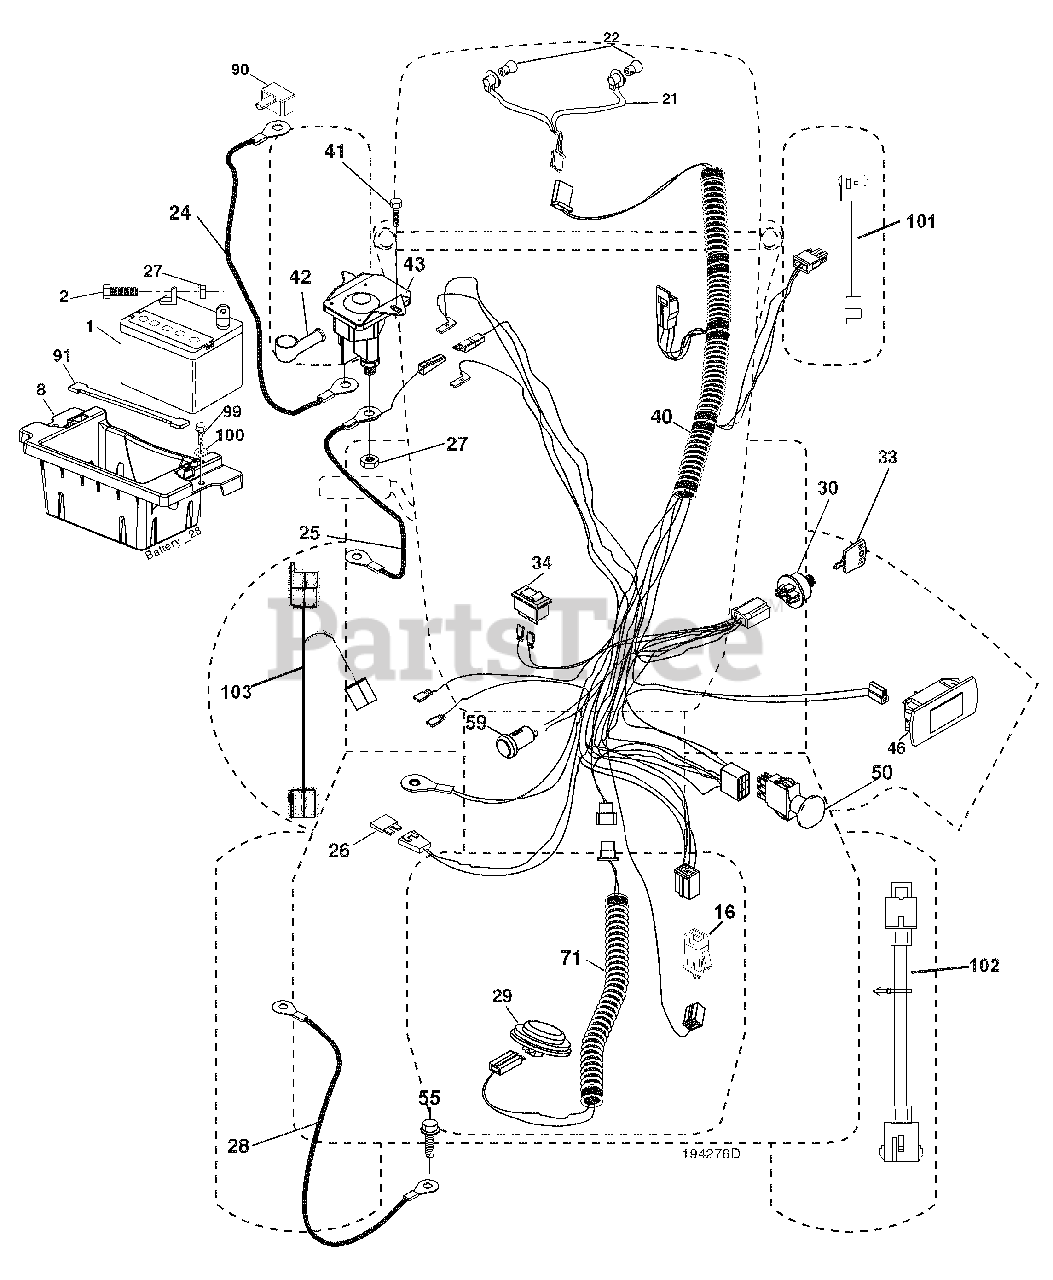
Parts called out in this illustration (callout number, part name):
1	Battery
2	Bolt Hex Hd 1/4-20 unc x 3/4
8	Battery Box
16	Switch Interlock
21	Harness Socket Light
22	Bulb, Light # 1156
24	Cable Battery
25	Cable Starter
27	Nut Keps Hex 1/4-20 unc
28	Cable Ground 21" Blk 6 Ga.
29	Switch Seat
30	Switch Ign
33	Key Ign Molded Generic
34	Switch Light/Reset
40	Harness Ign. Dash
41	Screw Thd Cut 1/4-20 x 1/2
42	Cover Terminal Red
43	Solenoid
46	Gauge Hourmeter
50	Switch PTO
55	Screw Thdrol 5/16-18 x 3/4
59	Outlet 12-Volt
71	Harness Ign
90	Cover Terminal Battery
91	Strap Battery
99	Screw Hexwsh Thdrol 1/4-20 x 3/4
100	Washer 9/32 x 7/8 x 16 Ga.
101	Pigtail MATNLK
102	Harness Pigtail K46 Te x ROS
103	Harness Pigtail 12V Outlet
